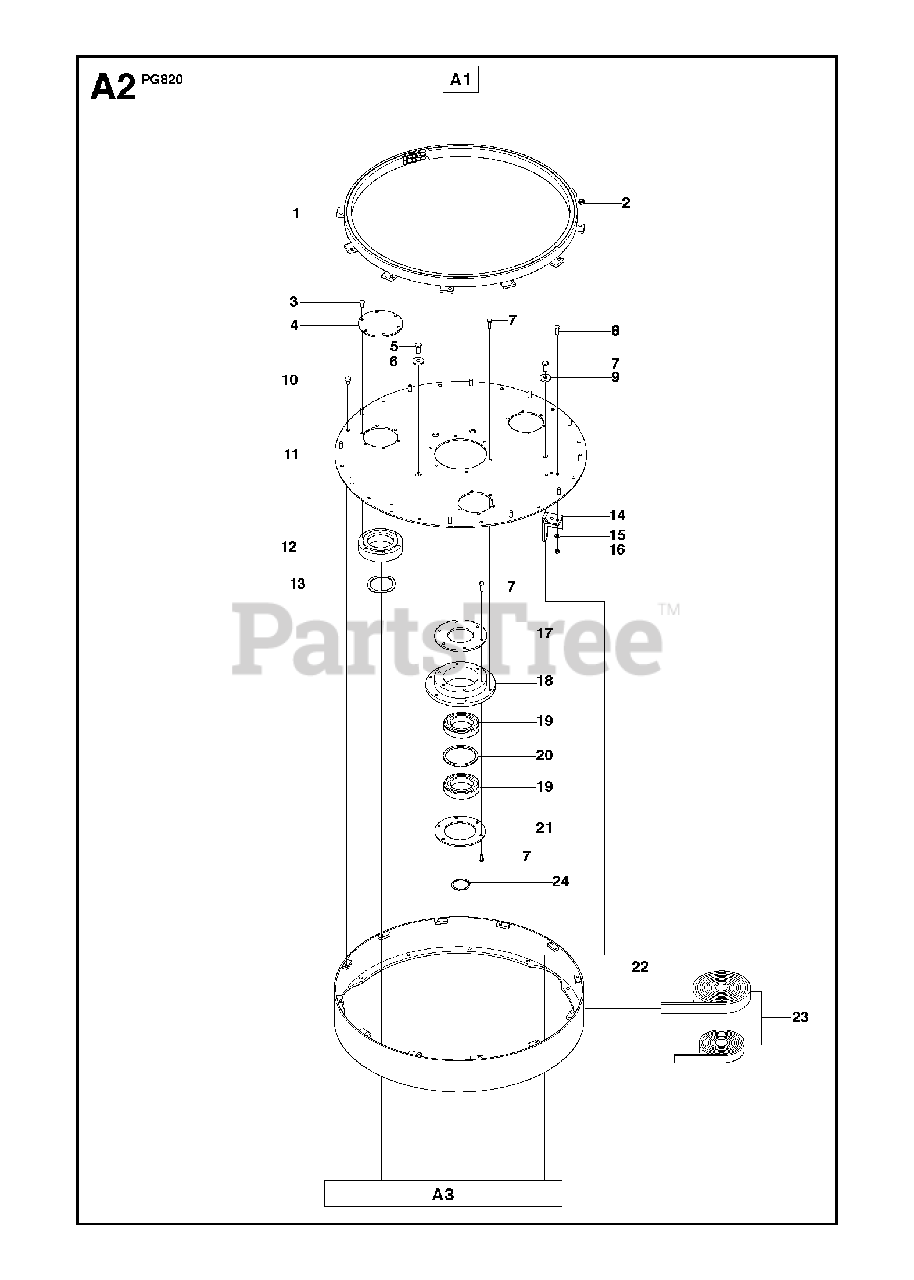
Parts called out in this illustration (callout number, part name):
2	HEXAGON LOCKING NUT
15	WASHER
16	HEXAGON LOCKING NUT
